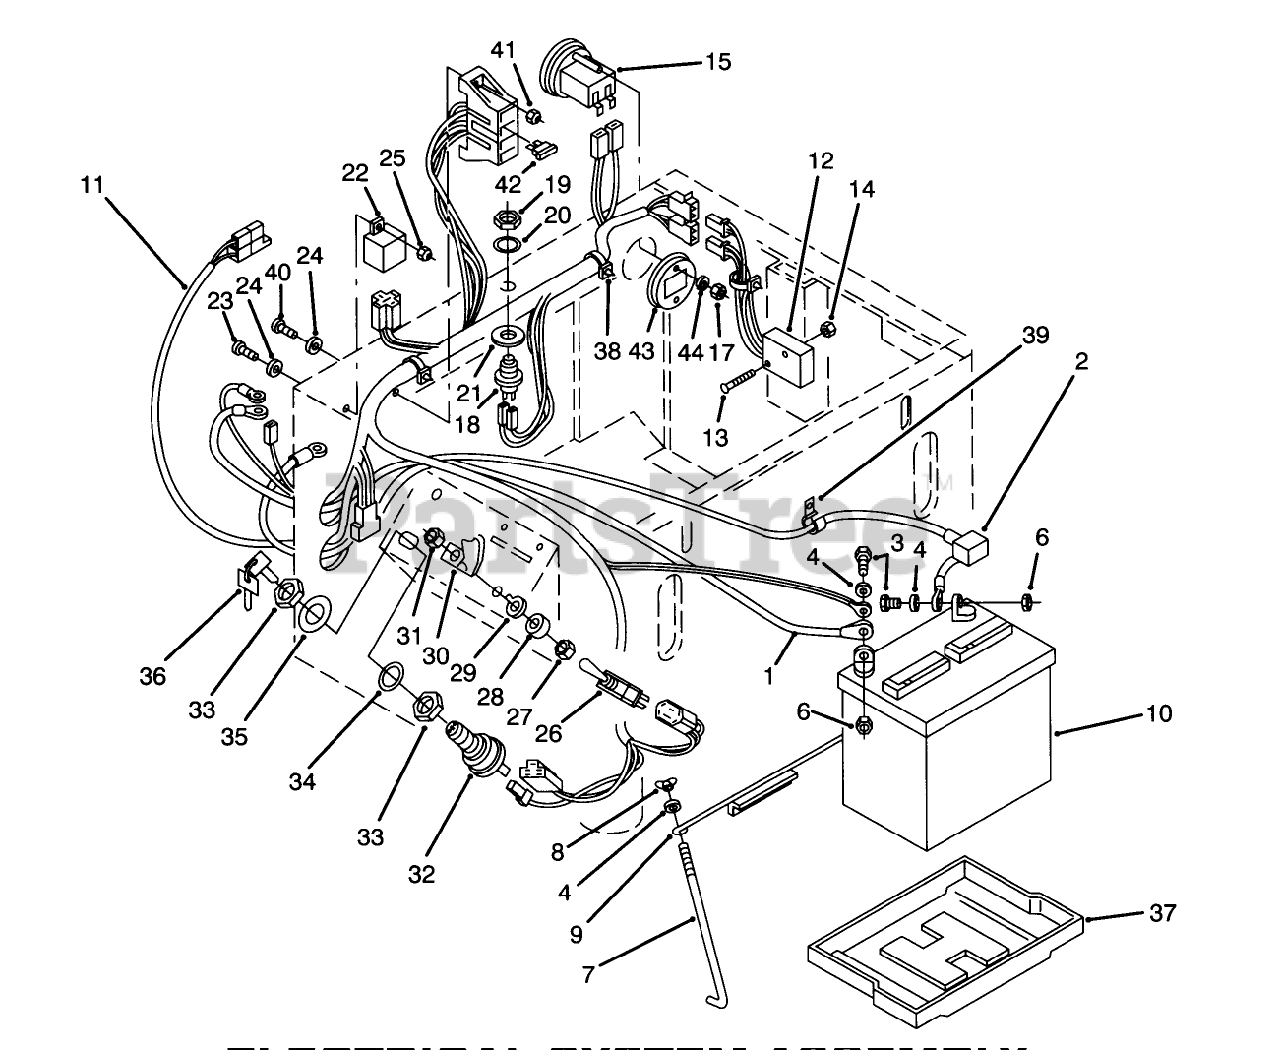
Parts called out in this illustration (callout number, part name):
1	WIRE ASM
3	SCREW-HH
4	WASHER-FLAT
6	NUT-LOCK, NI
7	HOOK-BATTERY RETAIN
8	NUT-WING
9	HOLDDOWN-BATTERY
13	SCREW-PPH
19	HEX-NUT 5/8-24 F/W 116194
21	WASHER-FLAT
22	RELAY
24	WASHER-FLAT
26	SWITCH-TOGGLE DPDT
28	WASHER-FLAT
29	TAB-WASHER
30	COVER-PTO SWITCH
31	*DISC**
32	SWITCH, KEY ASS'Y
33	HEX-NUT 13/16 UNEF
35	WASHER-SPECIAL
36	KEY-PADDED TORO CUT
37	TRAY-BATTERY
38	CLIP-SNAP IN
39	J-CLIP
43	CLAMP-HOUR METER
44	WASHER-LOCK
